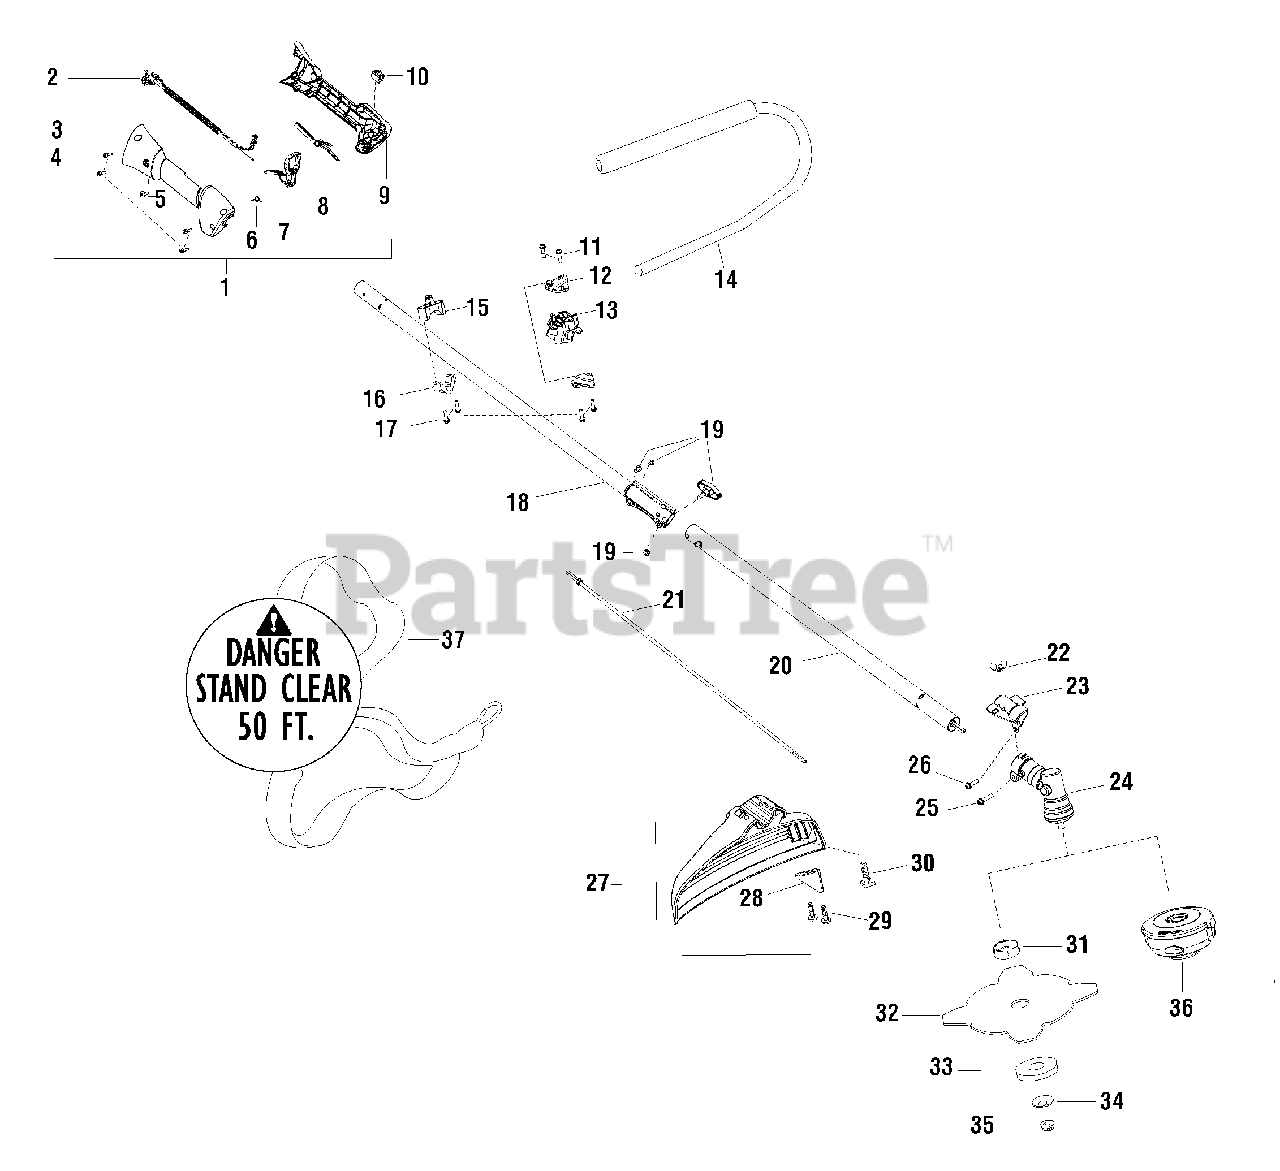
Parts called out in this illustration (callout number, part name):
1	Assy - Throttle Housing
2	Assy-Cable/Wire Harness
3	Housing-Throttle, RH
4	Screw
6	Spring-Trigger
7	Trigger
8	Lockout-Throttle
9	Housing-Throttle, LH
10	Kit-Switch
11	Screw 10-14 x 13/16
12	Clamp - Bracket
13	Clamp - Handlebar
14	Kit - Handlebar
15	Clamp - Upper Harness
16	Clamp - Lower Harness
17	Screw - 10-14 x .095
18	Assy-Driveshaft Upper
19	Kit - Knob / Screw
20	Kit - Lower Shaft
21	Flexshaft - Lower
22	Wingnut
23	Bracket - Shield
24	Gearbox
25	Screw - 12-24 x .960
26	Screw - 8-16 x .593
27	Kit-Shield
28	Limiter - Line
30	Bolt
31	Dust cup
32	Assy. - Blade
34	Washer - Belleville
35	Nut - Flange, LH
36	Head - Cutting
37	Shoulder Strap
